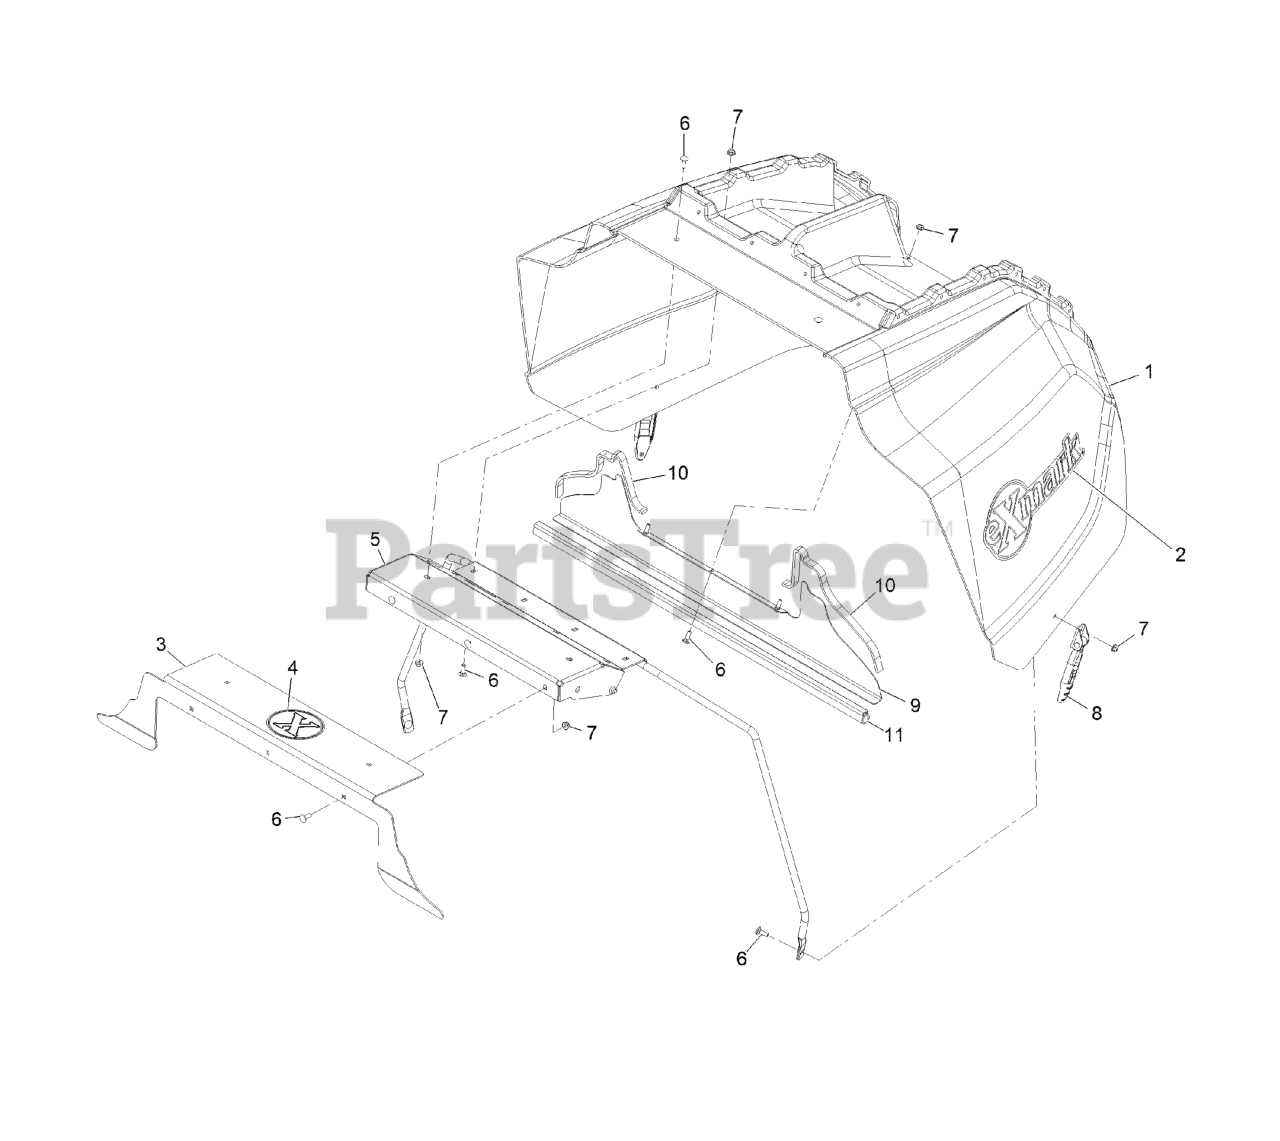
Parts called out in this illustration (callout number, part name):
1	HOOD,LZSD
2	DECAL-EXMARK
3	Block Off-Hood
4	DECAL-X-LOGO
5	SUPPORT-HOOD
6	BOLT-CARR
8	LATCH-RUBBER
9	Plate-Seal
10	SEAL-FOAM
11	Seal-Bulb
